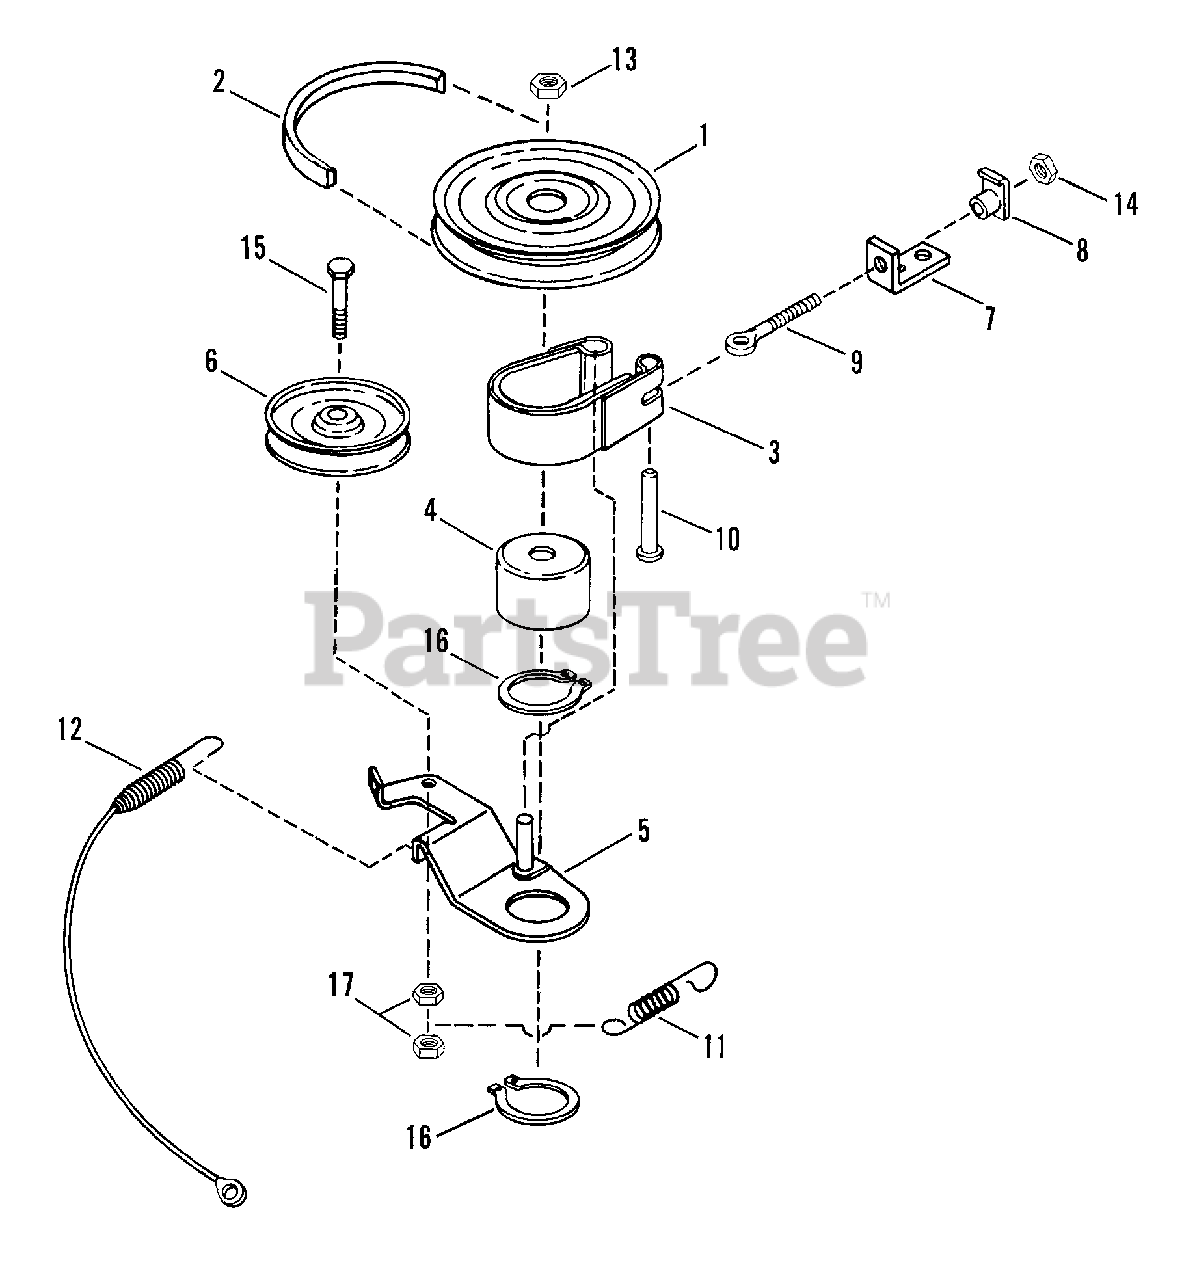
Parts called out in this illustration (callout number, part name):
1	PULLEY, Drive
2	BELT, Drive
3	BAND, Brake Assembly
4	DRUM, Brake
5	ASSEMBLY, Brake Arm
6	PULLEY, Idler
7	ANCHOR, Brake
8	NUT, 1/4-20 Tec.
9	BOLT, 1/4-20 Eye
10	PIN, Clevis, 1/4x1-1/4"
11	SPRING, Blade Brake
12	CABLE, Blade 28.5"
13	NUT, 3/4-16 Hex Jam
14	NUT, 1/4-20 Hex
15	SCREW, 3/8-24 x 2" Hex Head Cap (Gr. 5)
16	RING, 2" External Retaining
17	NUT, 3/8-24 Hex Lock
